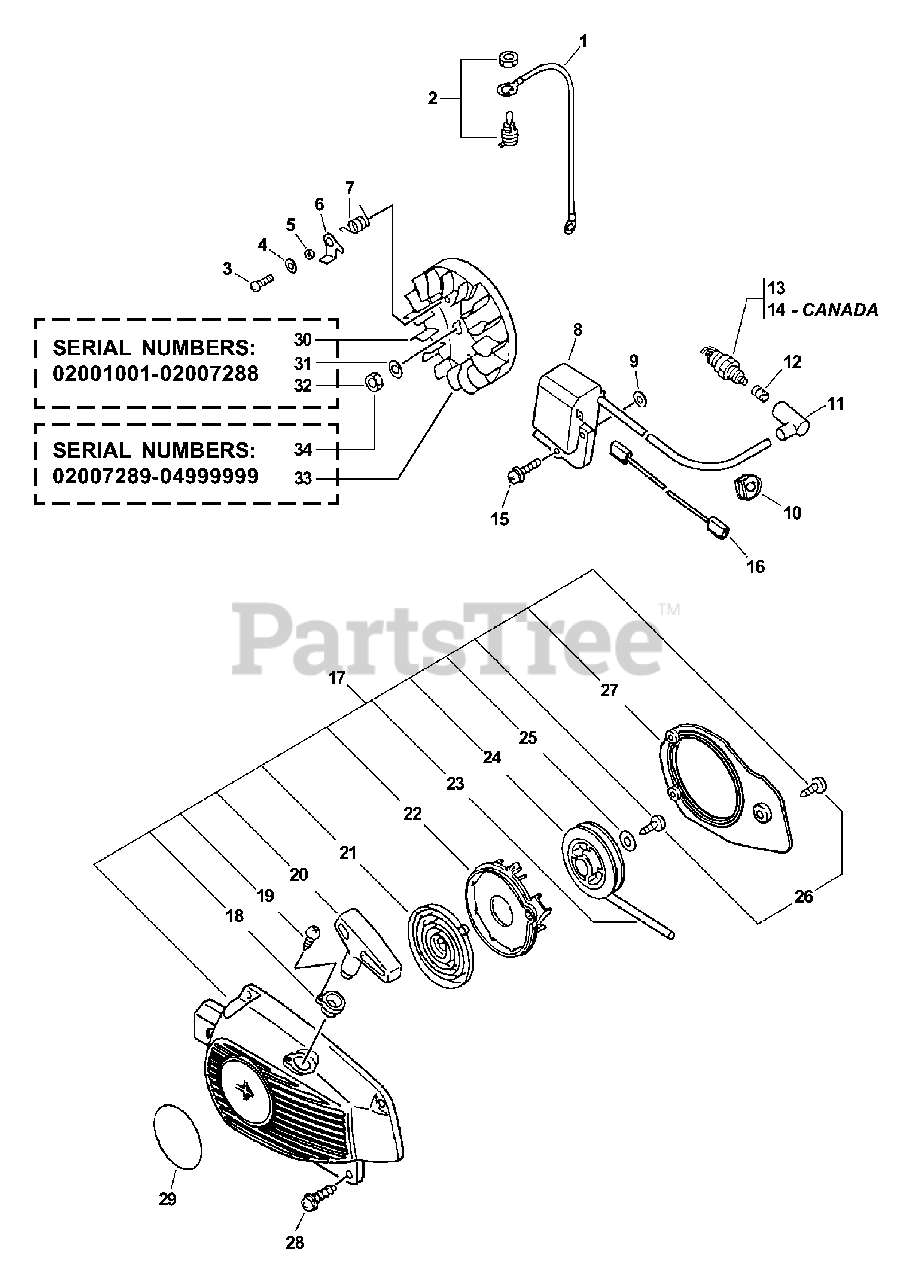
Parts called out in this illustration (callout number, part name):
1	LEAD - GROUND L= 100
2	SWITCH, ON-OFF
3	SCREW 5×12
4	WASHER 5.5×12×0.8
5	SPACER 5.2×8×2.1
6	PAWL, STARTER
7	SPRING, TORSION
8	COIL, IGNITION
9	WASHER 5.2×12×3
11	CAP, SPARK PLUG
12	TERMINAL, SPARK PLUG
13	SPARK PLUG - BPM8Y
14	SPARK PLUG - BPMR8Y
15	SCREW 5×22
16	LEAD - IGNITION L= 95
17	STARTER ASSY
18	GUIDE, ROPE
19	SCREW 3×14
20	GRIP, STARTER
21	SPRING, RECOIL
22	PLATE, STARTER
23	ROPE, STARTER 3.0×850
24	REEL, ROPE
25	WASHER 4.1×15.5×1T
26	SCREW 4×14
28	SCREW 4×16
29	LABEL, ECHO
30	FLYWHEEL
31	WASHER 8.5×16×1.2
32	NUT M8
33	FLYWHEEL
34	NUT, FLANGE M8
